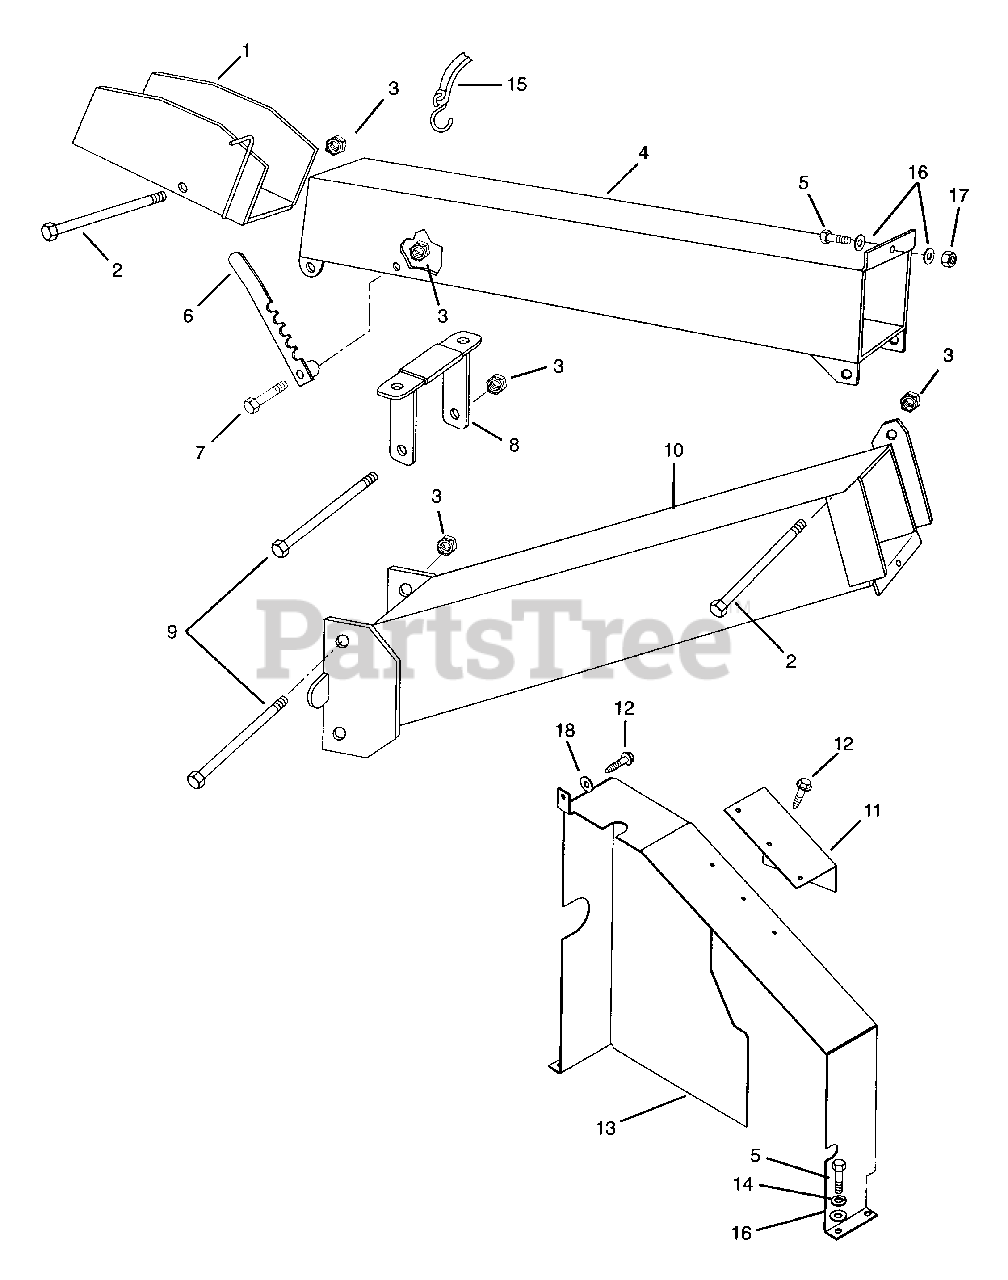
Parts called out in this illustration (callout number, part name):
2	Bolt-Hex .38-16 x 6.00 Grade 5
3	Nut-Locking-Center .38-16
4	Chute, Upper
5	Bolt-Hex .31-18 x 1.00 Grade 5
6	Lock Bar
7	Bolt-Hex .39-16 x 2.00 Grade 5
8	Chute Rest
9	Bolt-Hex .38-16 x 5.75 Grade 5
10	Lower Chute
11	Sheave Guard
12	Screw-Tapping .25-20 x .50 Hex Washer Head
13	Belt Guard Weldment
14	Washer-Locking .31 x .078
15	Rubber Strap - Hold Down
16	Washer-Flat-Steel .38 x .875 x .083
17	Nut-Locking-Center .31-18
18	Washer-Flat-Steel .312 x .734 x .065
